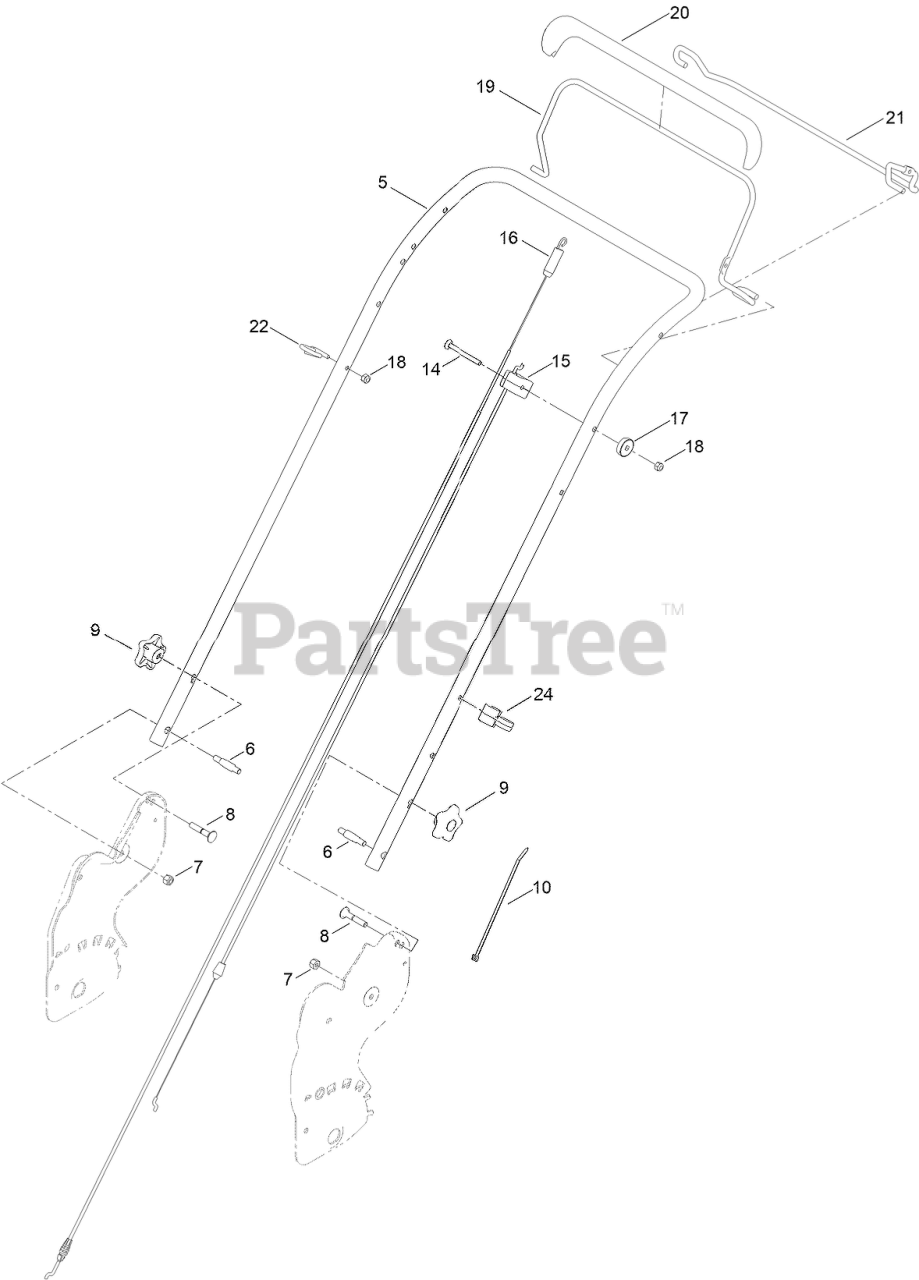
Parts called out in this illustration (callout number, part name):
5	HANDLE-CURVED
6	BOLT-SHOULDER, HANDLE
7	NUT-LOCK, NI
8	SCREW-CARR
9	KNOB-HANDLE
10	TIE-CABLE
14	SCREW-CARR
15	CABLE-BRAKE, FWD
16	CABLE-TRACTION, FWD
17	WASHER-CURVED
18	NUT-LOCK, NI
19	BAIL-BRAKE
20	COVER-BAIL
21	BAIL-TRACTION
22	GUIDE-ROPE
24	GUIDE-CABLE
